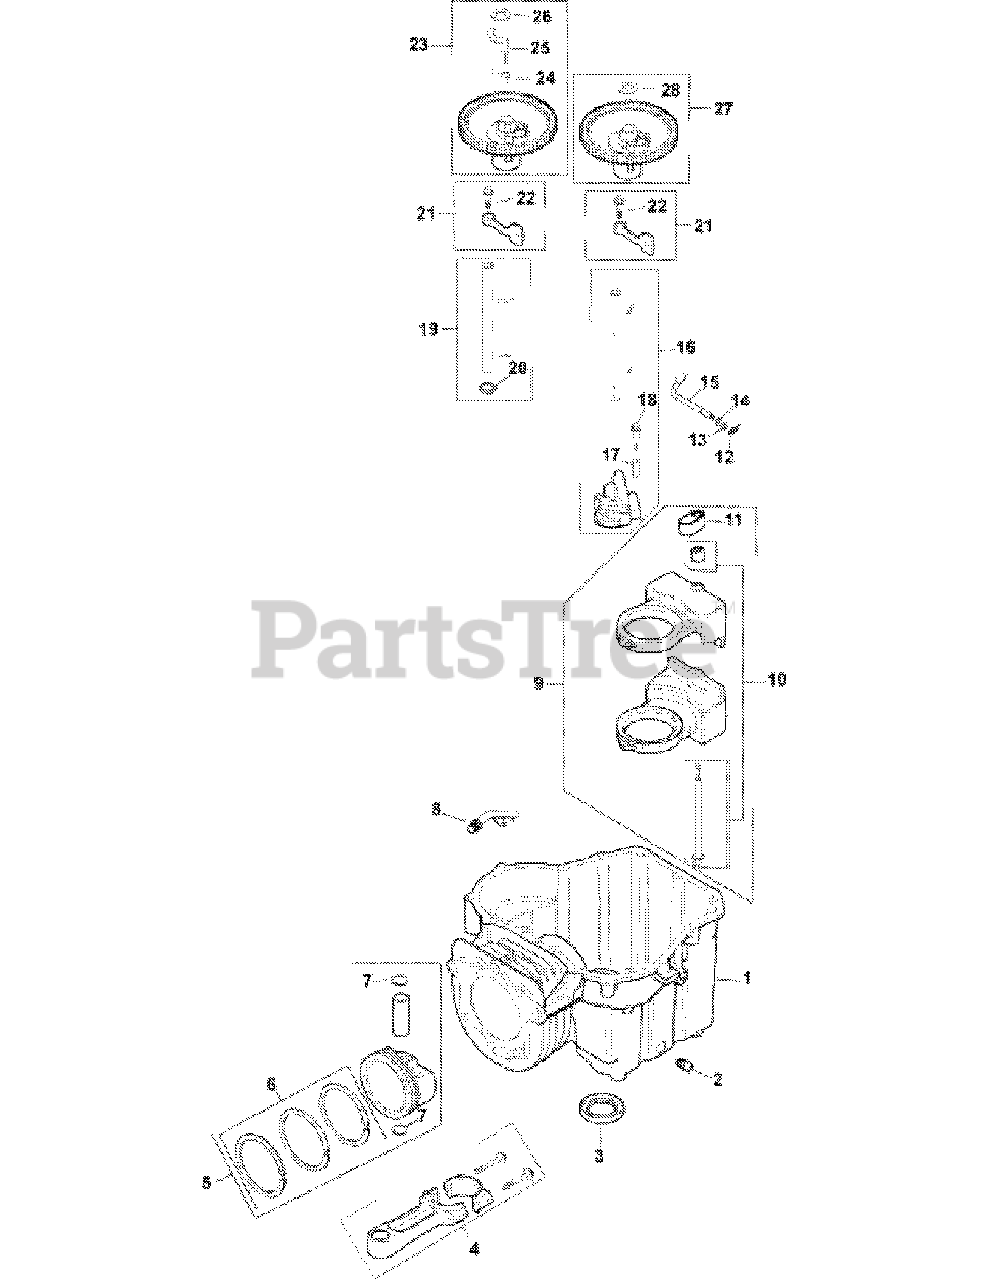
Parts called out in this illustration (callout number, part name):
1	CRANKCASE
2	PLUG, SQ HD PIPE 3/8"
3	SEAL, OIL
4	ROD, CONNECTING
5	KIT, PISTON W/RING SET (94MM)
6	RING SET (94 MM)
7	RETAINER, PISTON PIN
8	TUBE, DRAINBACK
9	KIT, BALANCE WEIGHT - DISC.
11	SHOE, GUIDE
12	CLIP, HITCH PIN
13	WASHER, FLAT 6 MM
14	WASHER, FLAT 1/4"
15	SHAFT, GOVERNOR CROSS
16	KIT, OIL PUMP ASSEMBLY
17	SPACER, OIL PUMP SCREW
18	SCREW, OIL PUMP
21	KIT, CAM LEVER ASSEMBLY
22	SCREW, SHD THD FRM M6X1X26
23	KIT, CAMSHAFT ASSEMBLY
24	SPRING, ACR
25	WEIGHT, ACR
26	WASHER, THRUST -ACR
27	KIT, CAMSHAFT ASSEMBLY
28	WASHER, THRUST -ACR
